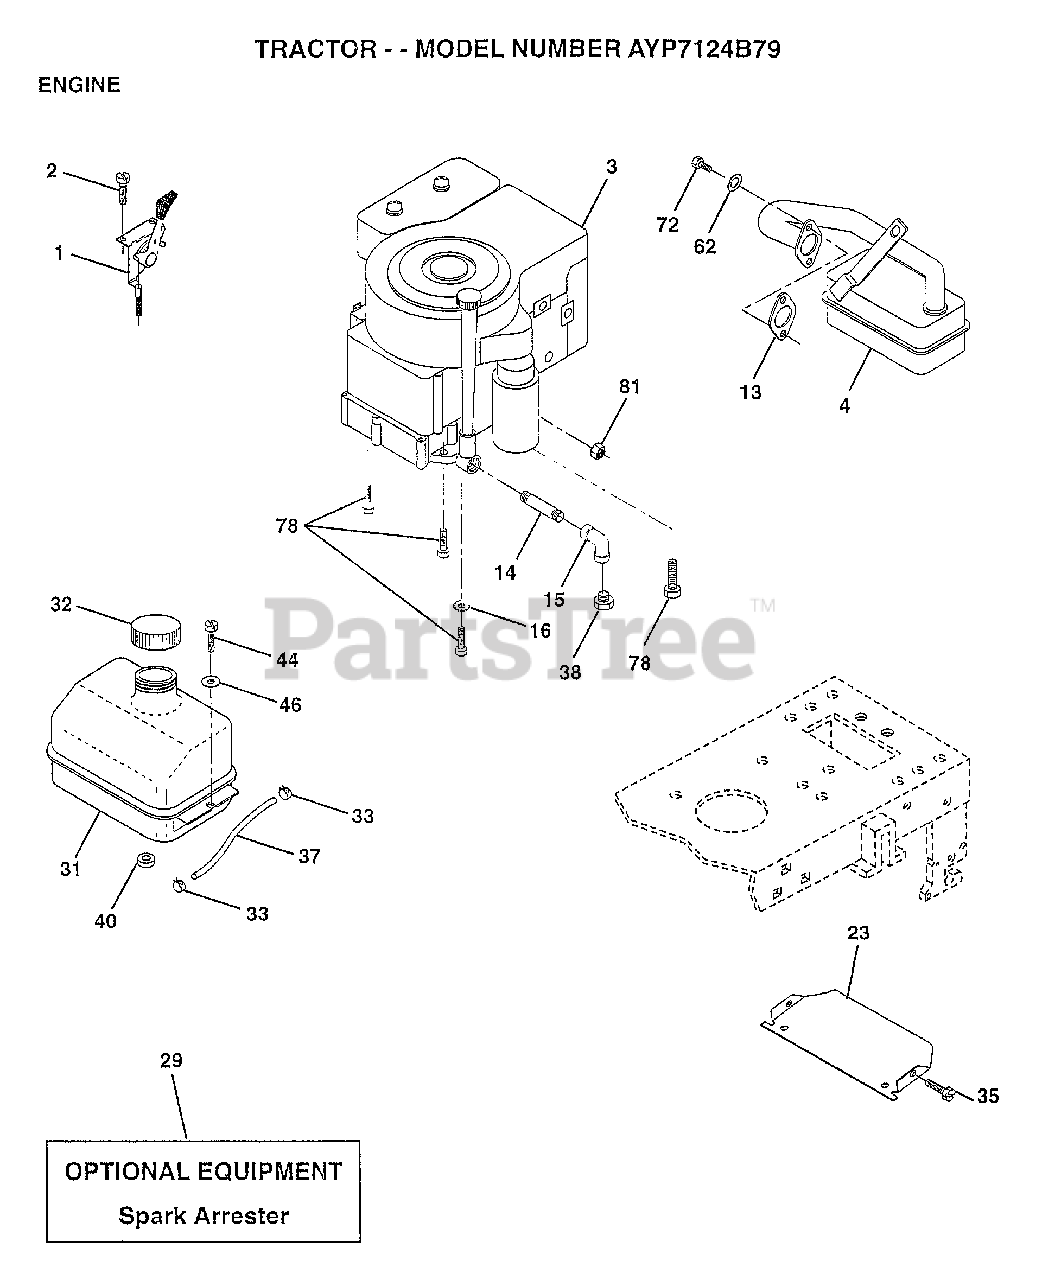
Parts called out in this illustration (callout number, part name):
1	CONTROL THROTTLE
2	SCREW LT
4	MUFFLER
13	GASKET ENG 1 313 LD TIN PLATED
14	PIPE NIPPLE
15	ELBOW
16	LOCKWASHER
23	SHIELD-HEAT
31	TANK.FUEL.LT.
32	CAP ASM FUEL
33	HOSE CLAMP
35	SCREW
37	LINE FUEL
44	SCREW HEX CRT
46	WASHER
62	LOCKWASHER
72	SCREW
78	SCREW
81	NUT
